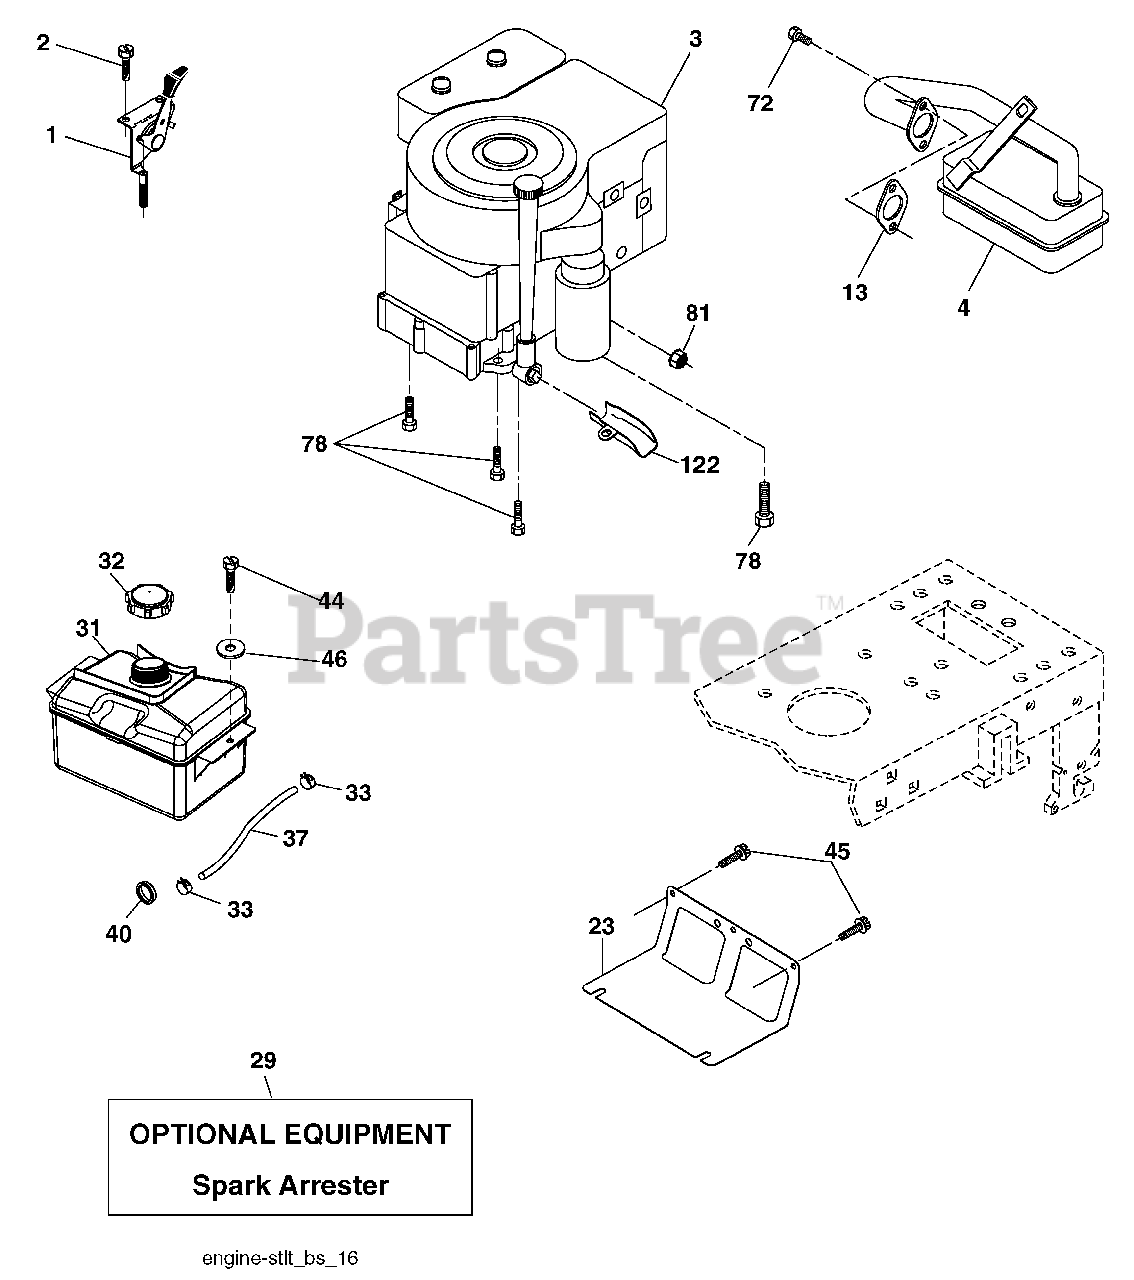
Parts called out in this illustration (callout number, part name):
1	Control Th/ch Flag
2	Screw Hex Thd Cut 1/4-20 x 1/2
4	Muffler Exhaust B&S
13	Gasket Eng 1 313 Id Tin Plated
23	Shield BRN/DBR Guard
29	Kit Spark Arrestor (Flat Scrn)
31	Tank Fuel Front
32	Cap Fuel
33	Clamp Hose
37	Line Fuel
40	Bushing Snap Nyl Blk Fuel Line
44	Screw Thdrol 1/4-20 x 3/4
45	Screw Hex Wsh Thdrol 3/8-16
46	Washer 9/32 x 7/8 x 16 Ga.
72	Screw Socket Head 5/16-18 x 3/4
78	Screw 3/8-16 x 1-1/4
81	Nut Keps Hex 1/4-20 unc
122	Extension Drain Oil
